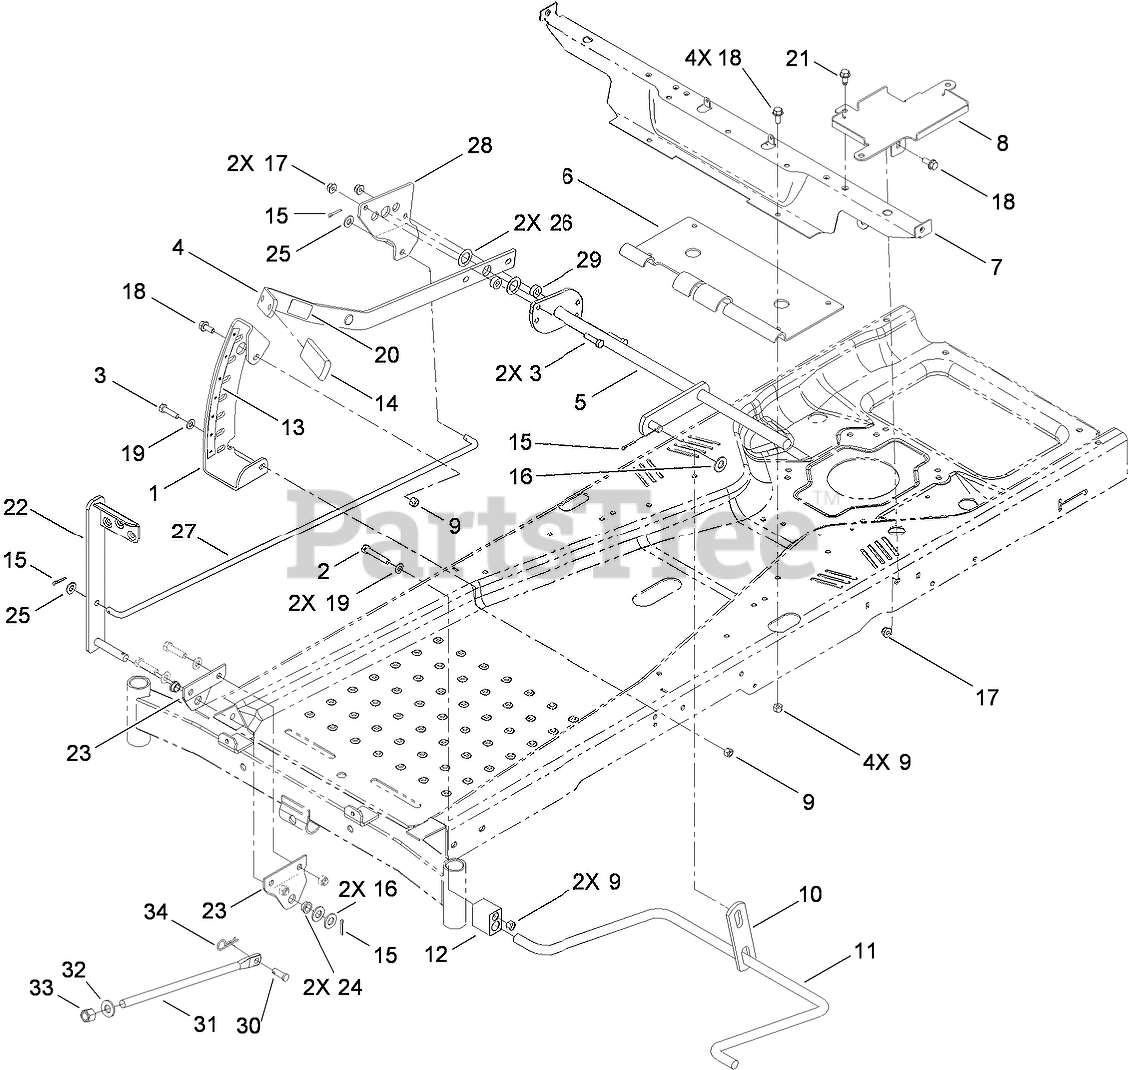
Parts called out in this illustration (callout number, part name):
1	SECTOR-HOC
2	SCREW-HH
3	SCREW-HH
4	LIFT ARM ASM
5	LIFT LEVER ASM
6	PLATE-LIFT
7	BRACKET-SEAT/PODS
8	TRAY-BATTERY
9	NUT-LOCK, NI
10	LINK-LIFT
11	ARM-LIFT, REAR
12	BLOCK-PIVOT
13	DECAL-HOC
14	GRIP-LEVER, LIFT
15	PIN-COTTER
16	WASHER-FLAT
17	NUT-HF, NI
18	SCREW-HHF
19	WASHER-PLAIN
20	DECAL-HOC
21	SCREW-HWH
22	PEDAL ASM
23	BRACKET-FOOTLIFT
24	BUSHING-FLANGE
25	WASHER-FLAT
26	WASHER-THRUST
27	ROD-LIFT
28	PLATE-FOOTLIFT
29	SPACER
30	PIN-CLEVIS
31	ROD-LIFT
32	WASHER-THRUST
33	NUT-LOCK, NI
34	PIN-HAIR
